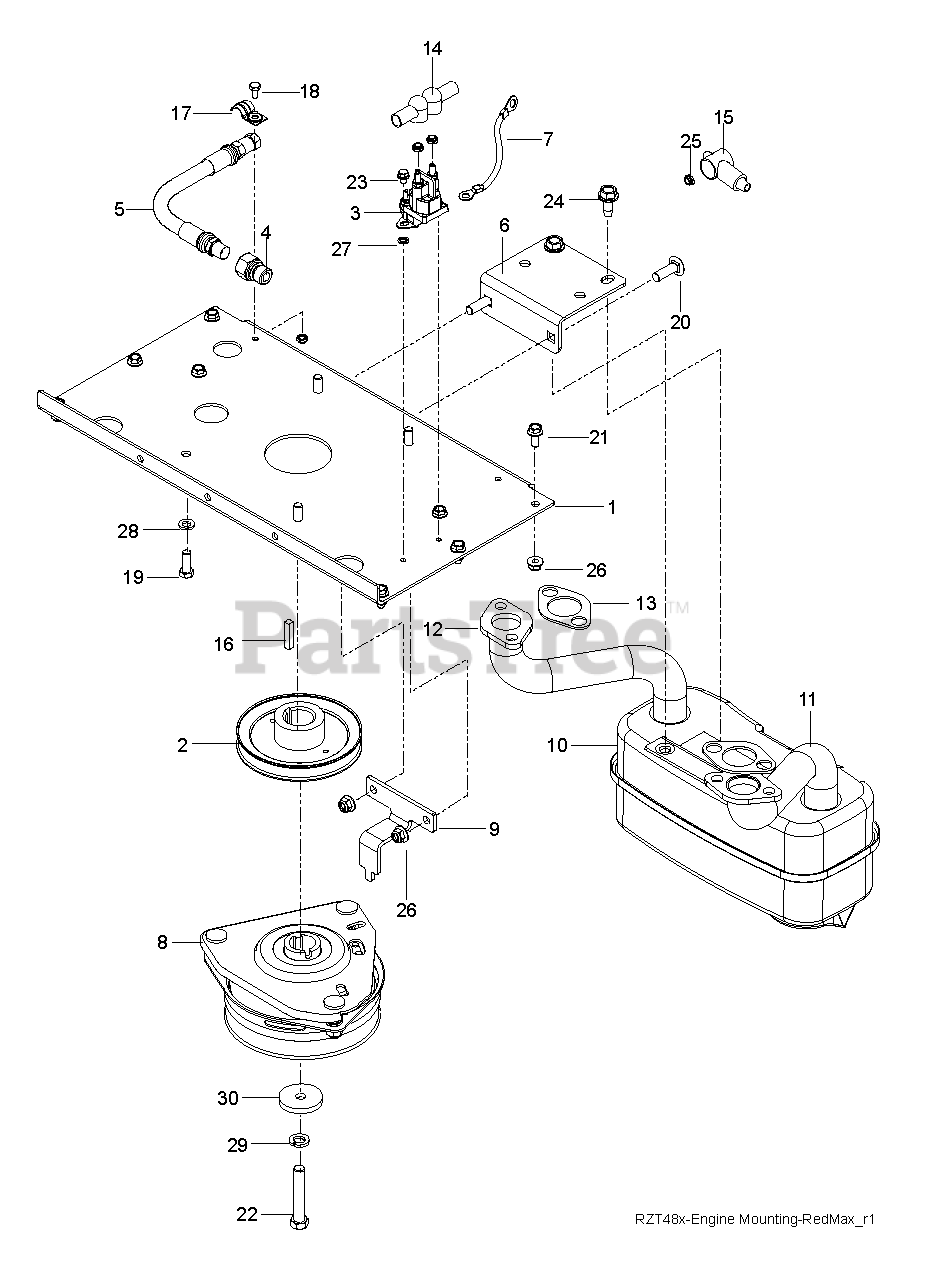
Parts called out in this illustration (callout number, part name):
1	PLATE.PNT.ENGINE.E-DIP
2	PULLEY.DRIVE.XMSN
3	SOLENOID.STARTER.BRASS.PLUNGER
4	ADAPTER, OIL DRAIN
5	HOSE.ASSEMBLY.OIL.DRAIN
6	BRKT, MUFFLER, BLK
7	CABLE POSITIVE
8	CLUTCH MZ ZTR GT.48/54"1.125"
9	BRACKET.CLUTCH.STOP.PNTX431
10	MUFFLER ASM TWIN
11	TUBE.EXHAUST.LH.FR961/FR730
12	TUBE.EXHAUST.RH.FR961/FR730
13	GASKET.EXHAUST.KAWASAKI
14	TERMINAL COVER
15	INSULATOR
16	KEY, 1/4 SQ X 1 1/4
18	HCS 1/4-20.
19	HCS 3/8-16X1.GRD.5.ZD
20	RHSSNB 5/16C X 1.0
21	HHFS 5/16-18 X 3/4
22	CLUTCH BOLT7/16-20X2.5 GR596HR
23	HWST 1/4C X 3/8
24	BOLT 5/16-18 X 3/4
25	JAM NUT 1/4C (2 2 PW01)
26	5/16-18 NYLOC FLANGE NUT
27	WASHER 1/4 INT TOOTH
28	SLW 3/8 STD
29	WASHER 7/16 LOCK
30	SPINDLE WASHER
